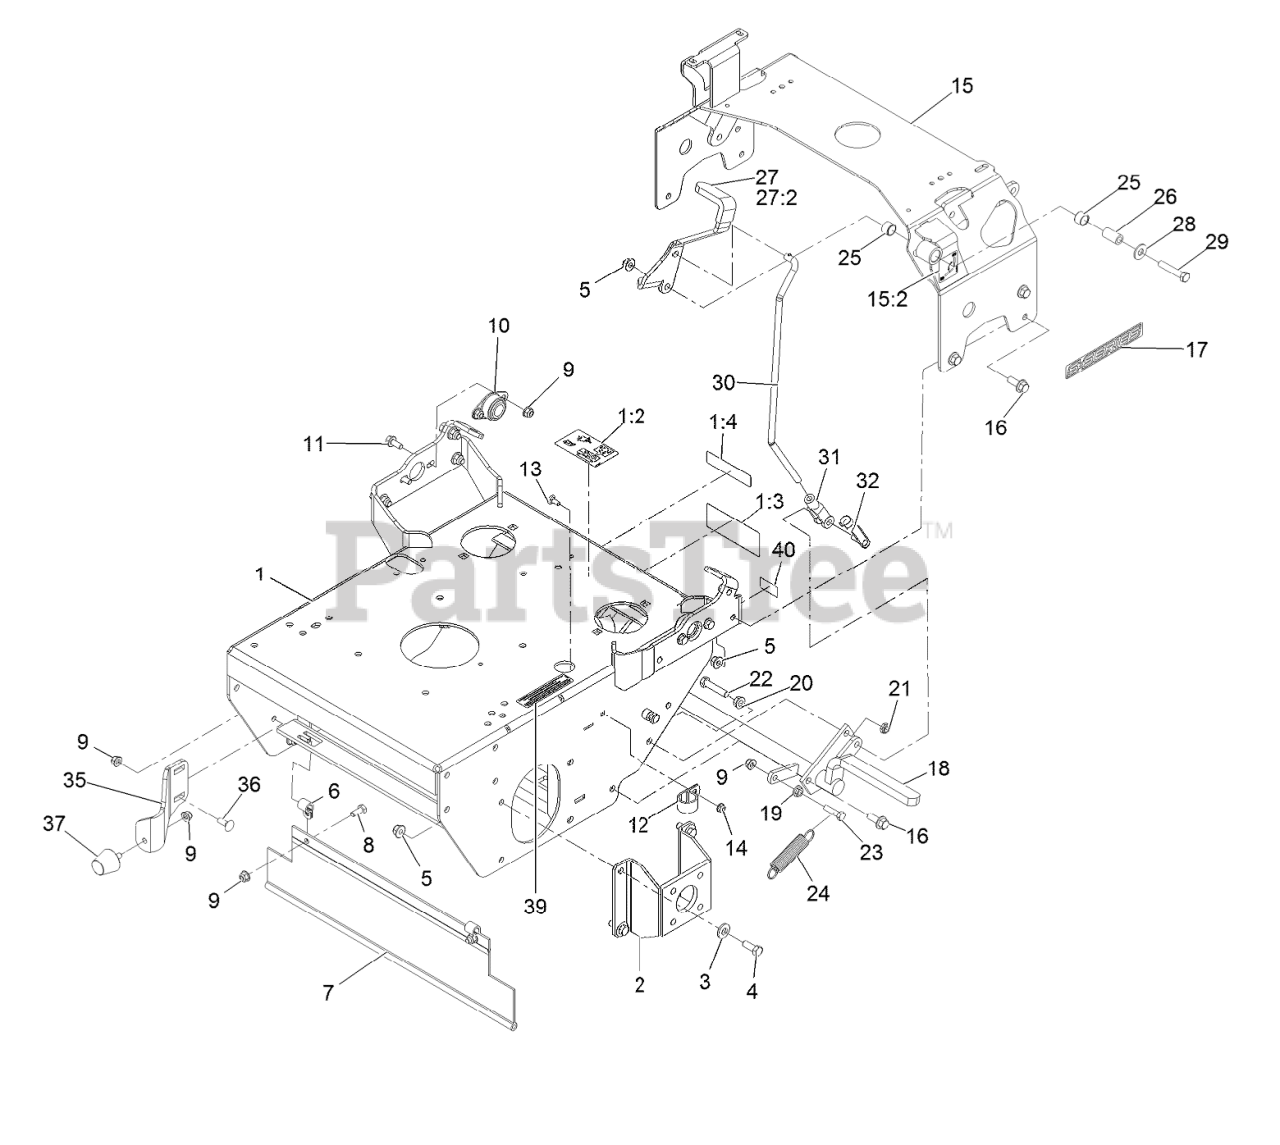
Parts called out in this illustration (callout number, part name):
1	ASM, ENGINE DECK W/ DECAL
1:2	DECAL-DRIVE RELEASE
1:3	DECAL-WARNING, SULKY
1:4	DECAL-WARNING
2	WLD,MOTOR MOUNT 36
3	WASHER-BELLEVILLE
4	SCREW-HH
5	NUT-HF, NI
6	CLIP-LOOM
7	SHIELD-DRAG
8	SCREW-HH
9	NUT-HF, NI
10	BEARING-FLANGE, SIDE
11	SCREW-HHF
12	CLIP-LOOM
13	SCREW-CARR
15	ASM, TANK SUPPORT W/ DECA
15:2	DECAL-PARK BRAKE, CE
16	SCREW-HHF 3/8-16 X 1
17	DECAL-S-SERIES
18	SHAFT-CROSS, BRAKE
20	NUT-HHF, WHIZ
22	SCREW-HH
23	SCREW-HH
24	SPRING-IDLER
25	SLEEVE-BUSHING
26	BUSHING-PIVOT
27	ASM, BRAKE LEVER W/ GRIP
27:2	GRIP-LEVER
28	WASHER-FLAT
29	SCREW-HH
30	LINKAGE, BRAKE
31	YOKE-LINKAGE, BRAKE
32	PIN-SPRING, CLEVIS
35	BRACKET-BUMPER
36	SCREW-CARR
37	BUMPER-RUBBER
39	DECAL-ARRESTOR, SPARK
40	Decal-Patent Ttco.Com
